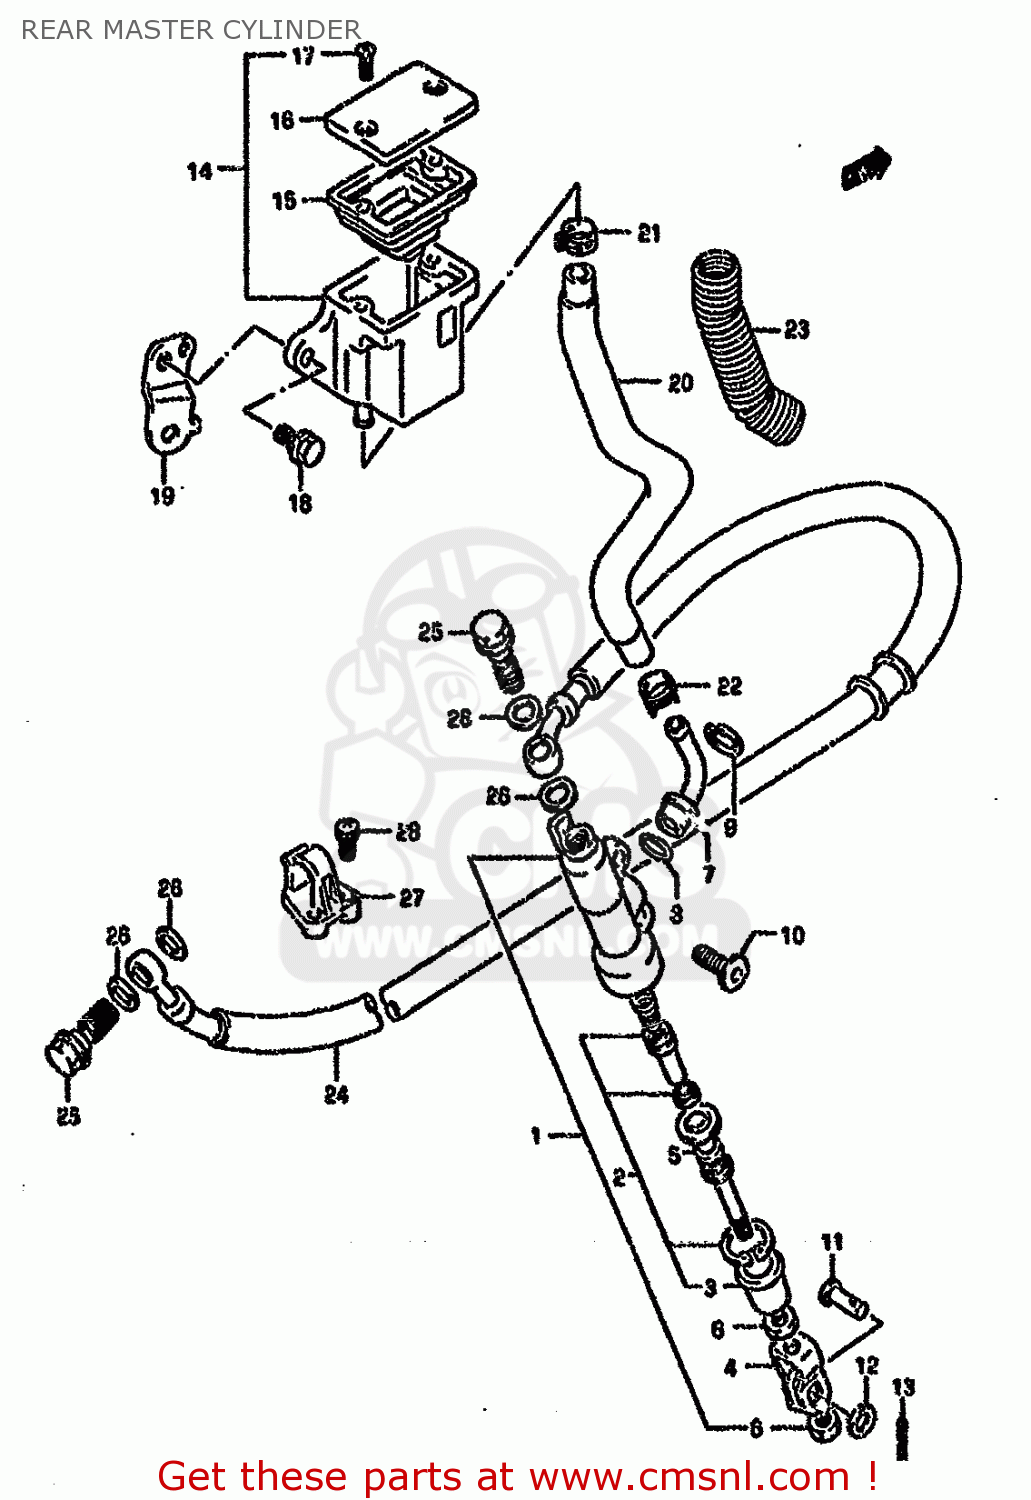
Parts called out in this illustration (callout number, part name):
1	CYLINDER ASSY,RR MASTER
2	PISTON/CUP SET
3	BOOT
4	YOKE
5	ROD,PUSH
6	NUT
7	CONNECTOR
8	O RING
9	CIRCLIP
10	BOLT(6X18)
11	PIN
12	WASHER
13	PIN
14	TANK ASSY,RESERVOIR
15	DIAPHRAGM
16	CAP
17	SCREW
18	BOLT
19	PLATE,RESERVOIR TANK
20	HOSE COMP,RESERVOIR TANK
21	CLIP
22	CLIP
23	SHIELD,RESERVOIR TANK HOSE
24	HOSE COMP,REAR BRAKE
25	BOLT UNION
26	WASHER(10X15X1.5)
27	GUIDE,RR BRAKE HOSE
28	SCREW
